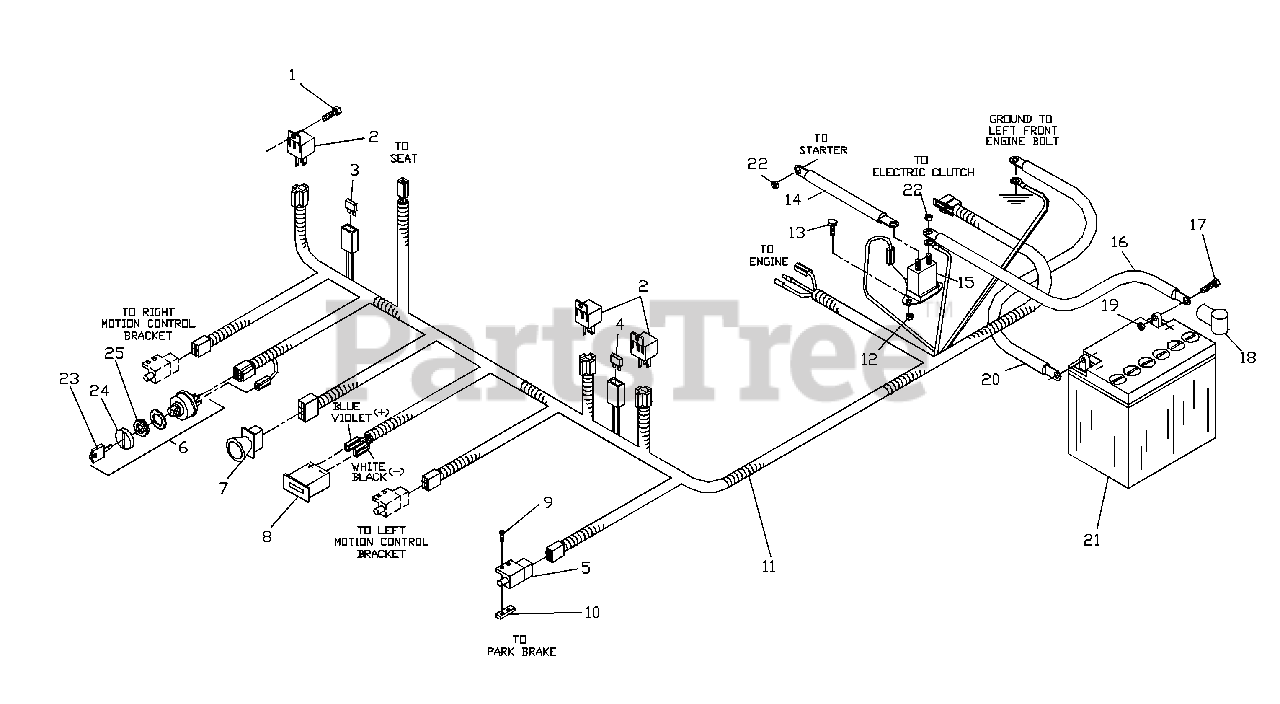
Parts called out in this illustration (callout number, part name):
1	#10 X 1/2 SELF TAPPING
3	7.5 AMP 32 VOLT ATO FUSE
4	20 AMP 32 VOLT ATO FUSE
5	INTERLOCK SWITCH
6	IGNITION SWITCH
7	BLADE SWITCH
8	HOUR METER
9	#10-24 X 5/8
10	TAPPED PLATE
11	WIRING HARNESS
12	NUT 1/4C CENTERLOCK
13	HCS 1/4C X 5/8
14	CABLE POSITIVE
16	CABLE POSITIVE, LONG
17	HCS 5/16C X 3/4
19	NUT 5/16C CENTERLOCK
20	CABLE NEG.
21	BATTERY
22	NUT 1/4C NYLOC
23	KEY, PADDED
